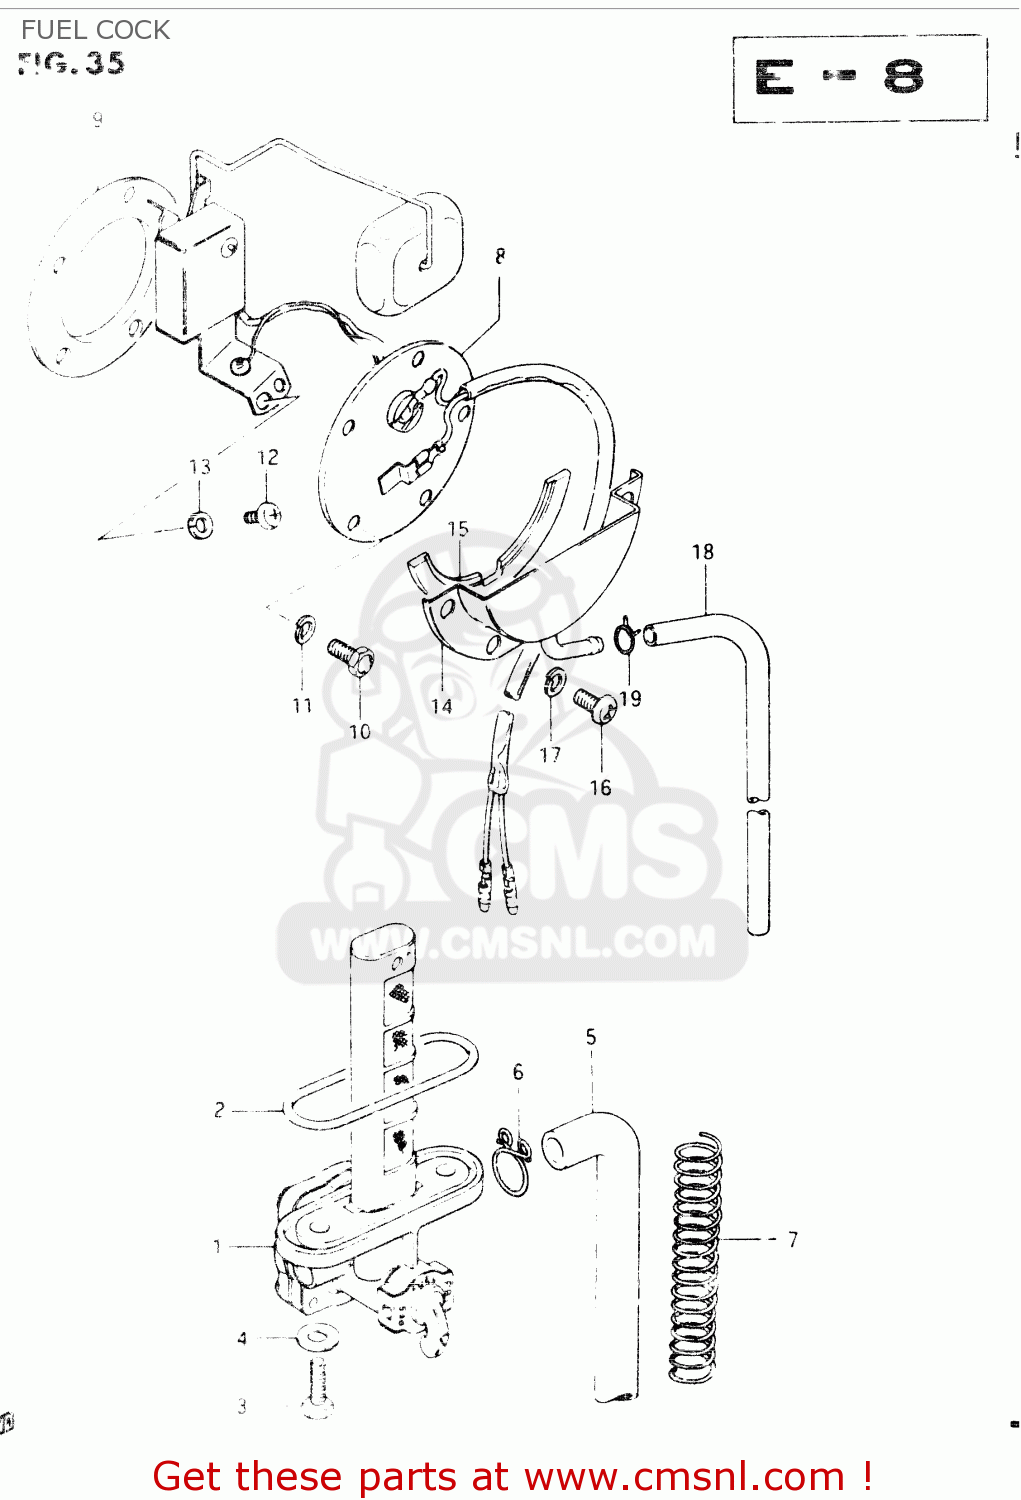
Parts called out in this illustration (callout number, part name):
1	COCK ASSY,FUEL
2	O RING
3	BOLT(6X20)
4	GASKET
5	HOSE
6	CLIP
7	SPRING
8	GUAGE, FUEL LEVEL
9	GASKET,FUEL LEVEL GAUGE (NAS)
10	BOLT
11	LOCK WASHER
12	SCREW 5X10
13	LOCK WASHER
14	PLATE,FUEL DRAIN
15	GASKET (NAS)
16	SCREW
17	LOCK WASHER
18	HOSE,FUEL
19	CLIP
